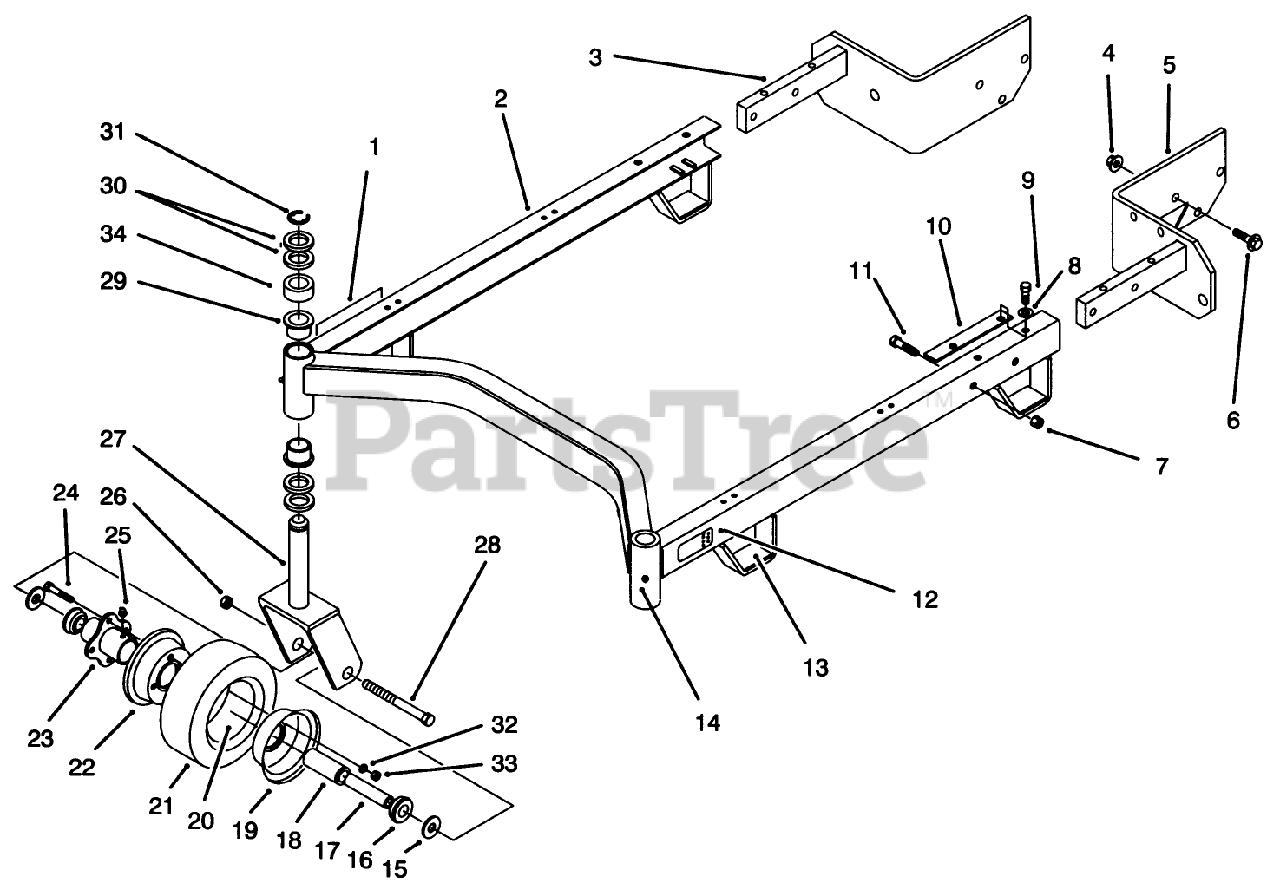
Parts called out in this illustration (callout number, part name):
1	DECAL-HOC, RH
2	Suspension Frame W.A.
3	Bracket RH
4	NUT-HF
5	Bracket-LH
6	SCREW-HHF
7	NUT-LOCK, CONE
8	WASHER-FLAT
9	SCREW W/PATCH
10	SHIM-CARRIER
11	SCREW-HH
12	DECAL-HOC, LH
13	CUSHION-RUBBER
14	FITTING-GREASE
15	WASHER-FLAT
16	BEARING-OUTSIDE
17	SPANNER-TIRE
18	BEARING-ROLLER
19	MALE WHEEL HALF
20	TUBE-INNER (W/VALVE)
22	FEMALE WHEEL HALF
23	HUB-CENTER
24	WHEEL BOLT
25	FITTING-GREASE
26	NUT-HEX
27	Fork
28	SCREW-HH
29	Bushing
30	WASHER-THRUST
31	RING-RETAINING
32	WASHER-LOCK
33	NUT-HEX
34	SPACER-CASTOR
